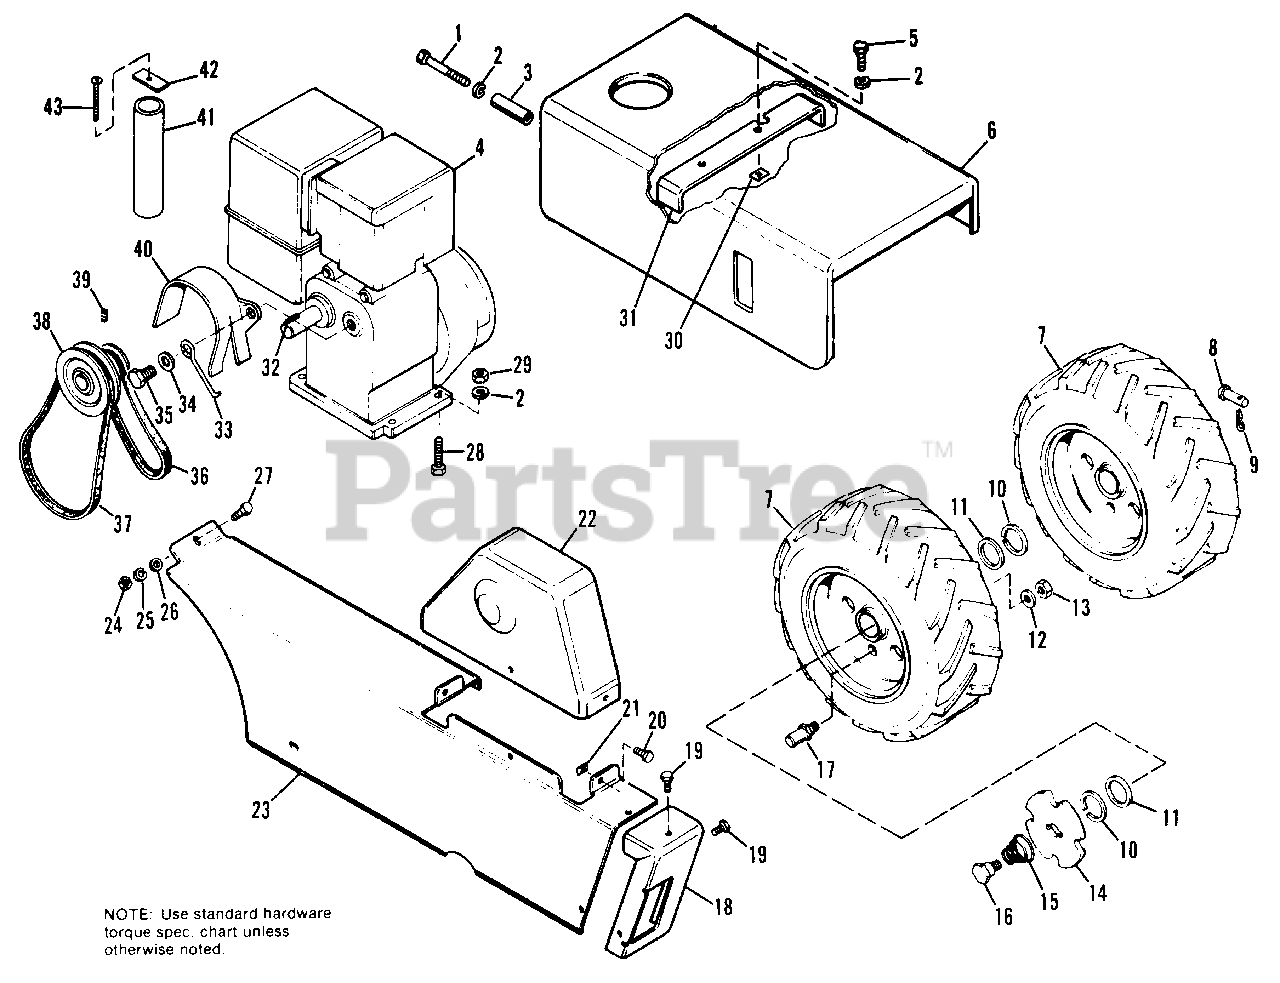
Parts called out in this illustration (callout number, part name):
1	CAPSCREW, Hex Hd., 5/16-18 x 3-1/4
2	LOCKWASHER, 5/16
5	CAPSCREW, Hex Hd., 5/16-18 x 3/4
6	HOOD ASSY.
7	WHEEL & TIRE ASSY.
8	PIN
9	PIN, Clip
10	RING, Retaining
11	WASHER, Special
12	WASHER, Plain, 5/16
13	LOCKNUT, Hex, 3/8-16
16	BOLT, Shoulder
18	SUPPORT, Belt Cover
19	SCREW, Taptite, 1/4-20 x 3/8
20	SCREW, Self Tapping, 1/4-20 x 5/8
21	NUT, Speed
22	COVER, Top Belt
23	COVER, Lower Belt
24	NUT, Hex, Full, 1/4-20
25	LOCKWASHER, 1/4
26	WASHER, Plain, 1/4
27	CAPSCREW, Hex Hd., 1/4-20 x 1/2
28	CAPSCREW, Hex Hd., 5/16-18 x 1-1/2
29	NUT, Hex Full, 5/16-18
30	NUT, Retainer, 5/16-18
32	KEY
33	ROD, Guide
34	LOCKWASHER, Int., 1/2
35	CAPSCREW, Hex Hd., 1/2-20 x 1
36	V-BELT (Transmission Drive)
37	V-BELT (Rotor Drive)
38	PULLEY, Engine
39	SETSCREW, 5/16-18 x 3/8
40	STOP, Belt
43	SCREW, Machine, #10-32 x 3
